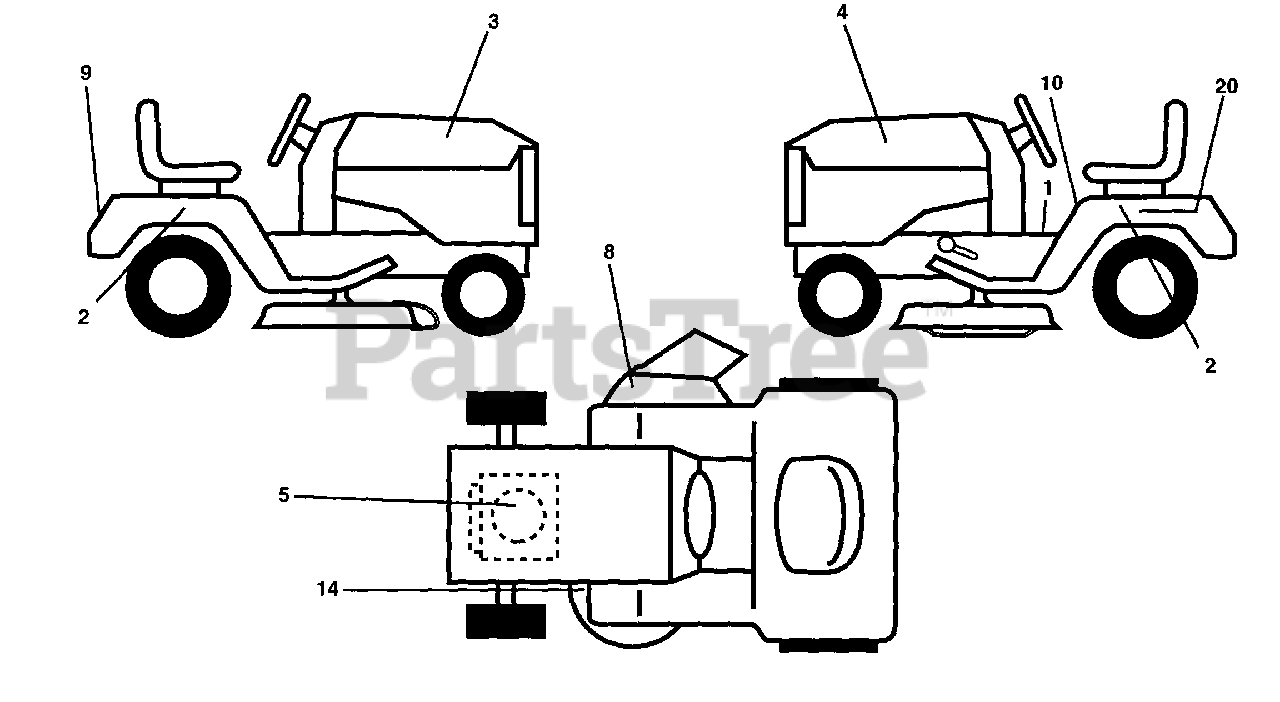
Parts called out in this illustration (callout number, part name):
1	Decal Oper Step Thru Eng/Fr
2	Decal Fender Ajuto Husq. Radius
3	Decal Hood LH
4	Decal Hood RH
5	Decal HP Engine
8	Decal Warning
9	Decal Fender Husq
10	Decal Fender Danger Eng/Fr
14	Decal V-Belt Schematic
20	Decal Bat Dan/Psn
